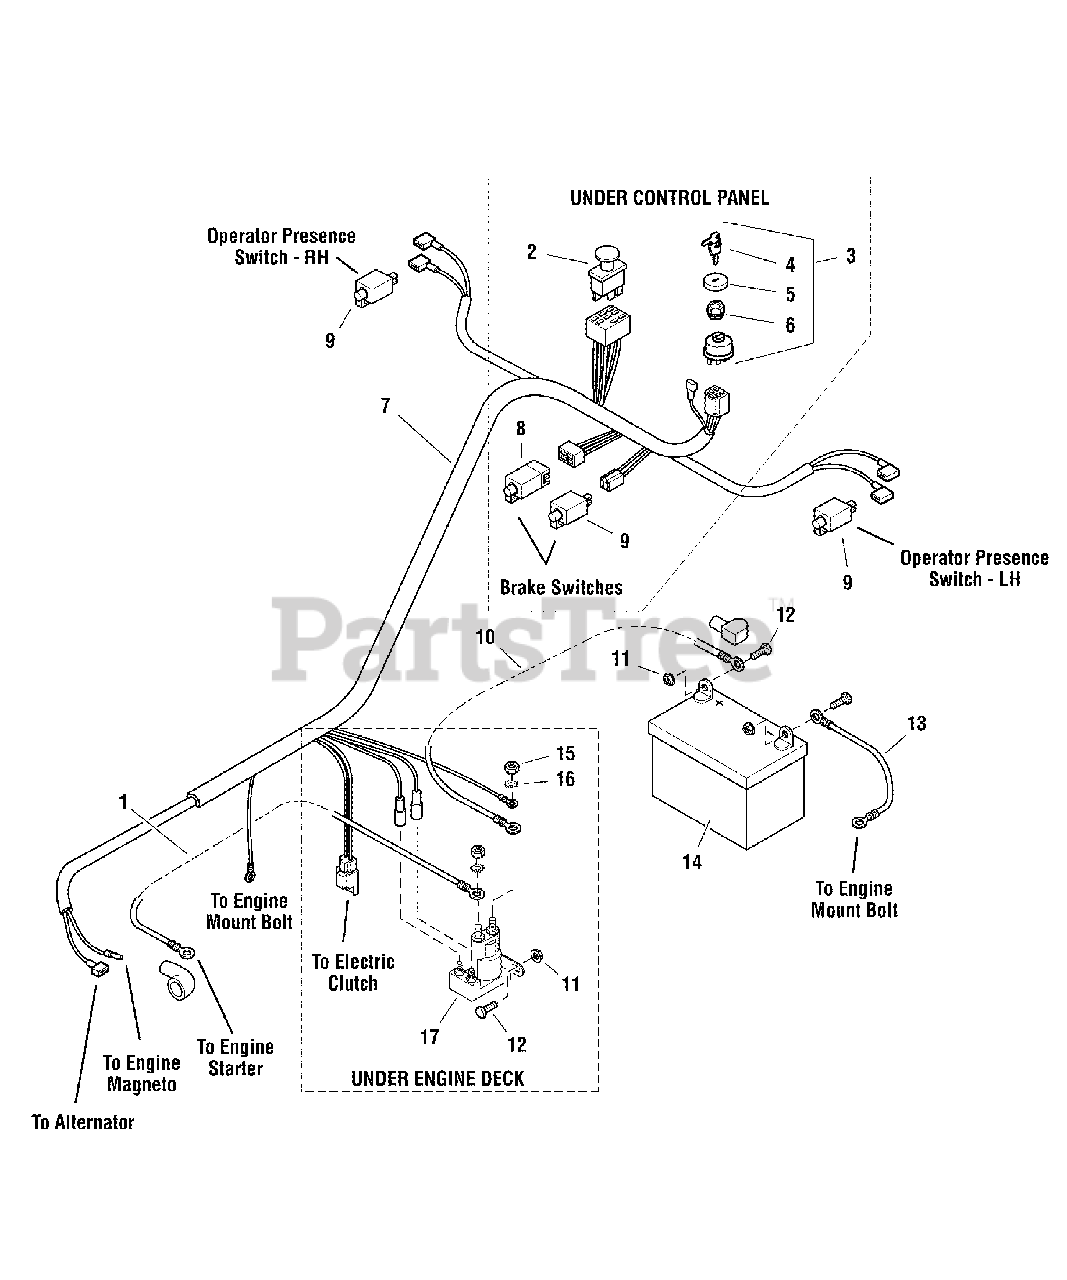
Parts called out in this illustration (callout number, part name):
1	POSITIVE (+) BATTERY CABLE, 30"
2	SWITCH, PTO
3	SWITCH, IGNITION, 6 POST
4	KEY, IGNITION MOLDED SET
5	COVER, PLASTIC, SNAP ON
6	PLASTIC NUT
7	WIRE HARNESS
8	SWITCH, Plunger, NO/NO
9	SWITCH, Plunger, NC
10	POSITIVE (+) BATTERY CABLE, 22"
11	NUT, 1/4-20 Hex Serrated Flange
12	BOLT, 1/4-20 x 3/4
13	NEGATIVE (-) BATTERY CABLE, 22"
14	BATTERY, Lawn & Garden, 12V (BCIU1, 340 CCA)
15	NUT, Hex Jam, 5/16-24
16	WASHER, Light Lock, 5/16
17	SOLENOID
18	GUARD, WIRE - RED
